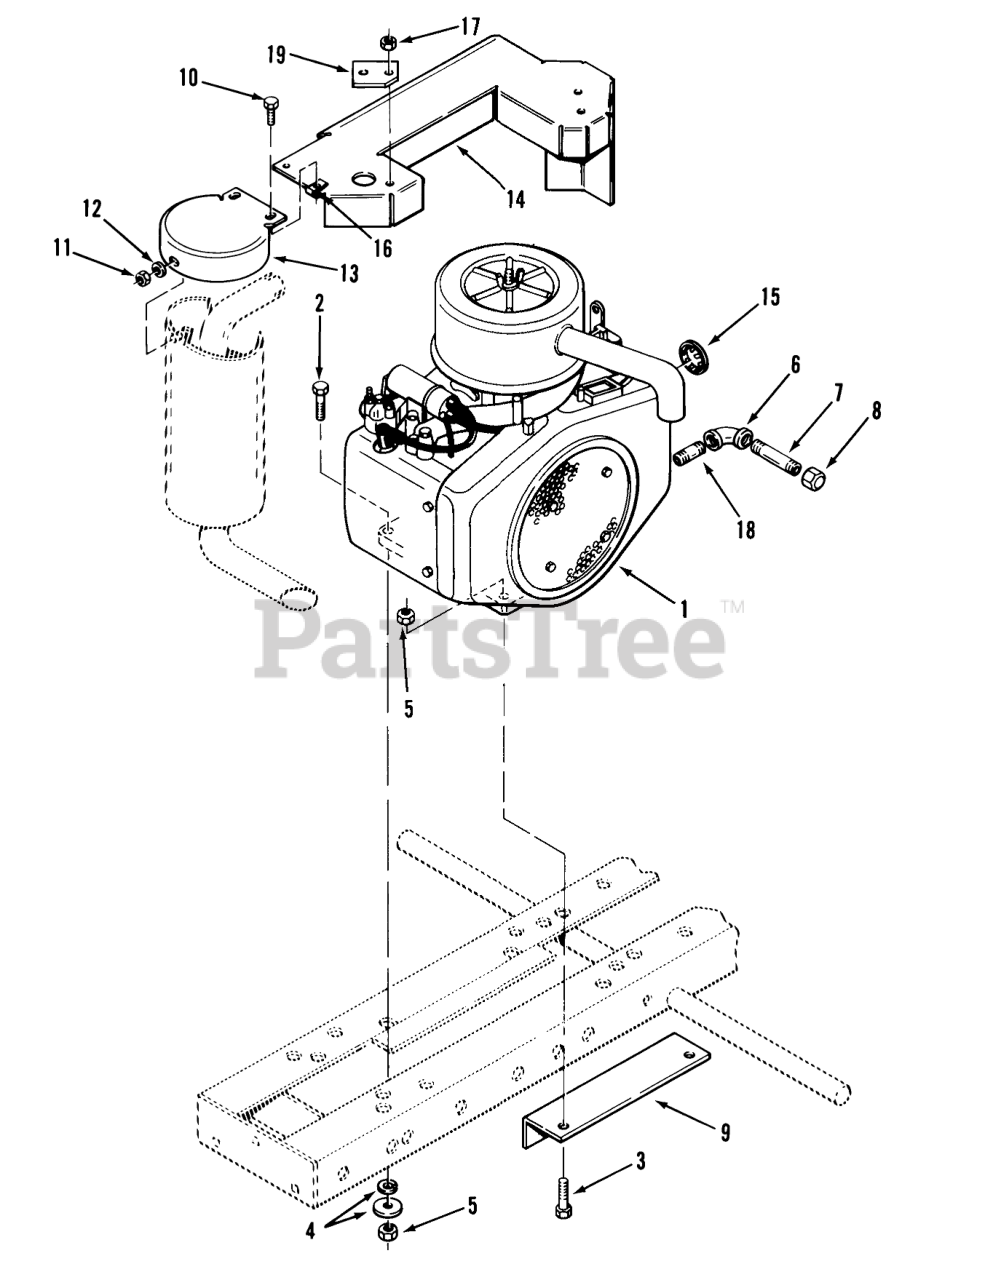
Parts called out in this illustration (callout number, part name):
1	Engine (Illustrated) 19 HP Kohler KT-19S Spec 49110-01-19KE01 Only
1	Engine 19 HP Kohler KT-19S Spec 49146-01-19KE02 Only
2	Bolt 3/8-16 x 1 1/2 Grade 8-01-19KE01 Only
2	Bolt 3/8-16 x 1
3	Bolt 3/8-16 x 1
4	WASHER
4	LOCKWASHER
5	Nut 3/8-16 Grade 8
6	Elbow 3/8
7	Nipple 3/8 x 5
8	Cap
9	Engine Support
10	Screw
11	Nut
13	CAP-MUFFLER SHIELD
14	Heat Shield
14	ASSY HEAT SHIELD
15	Plug Button
17	Flanged Nut
18	Nipple 3/8 x 1 1/2
19	Cover (Used on 01-19KE01 with 110079 Shield-Illustrated)
